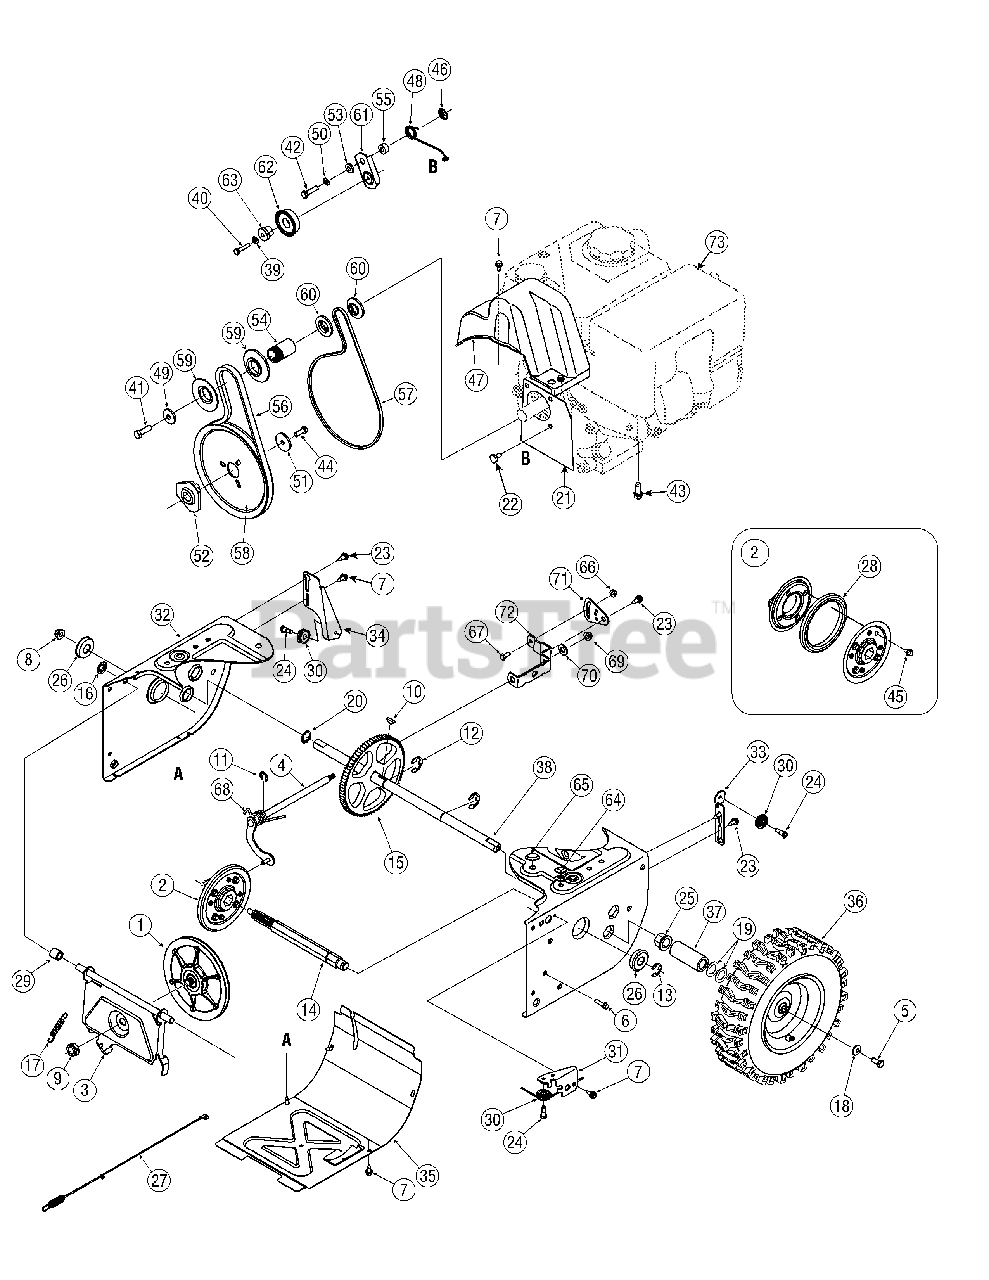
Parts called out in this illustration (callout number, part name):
1	Disc Assembly, Friction Wheel
2	Friction Wheel Assembly, 5.5 OD
3	Support Bracket, Friction Wheel
4	Shift Assembly, Rod
5	Hex Screw, 5/16-24, .750, Gr5
6	Screw, 1/4-20, 1.000
7	Screw, 1/4-20 x .625
8	Nut, Flange Lock, 3/8-16, Nylon
9	Nut, Flange, 5/8-18
10	Key, Hi Pro, 3/16 x 3/4 Dia.
11	E-ring, .500 Dia.
12	E-ring, Retaining, .875 Dia.
13	E-ring, .750 Dia.
14	Hex Shaft, .8125, 7-Tooth
15	Gear, 80-Tooth
16	Speed Nut, .500
17	Extension Spring
18	Washer, Bell, .340 x .872 x .060
19	Washer, Flat, .793 x 1.24 x .060
20	Washer, Flat, .75 x 1.00 x .060
21	Plate, Cover
22	Shoulder Screw
23	Screw, Shoulder, .37 x .105, 1/4-20
24	Screw, 1/4-28, .375
25	Bearing, Hex Flange x .75 ID
26	Bearing, Ball, 17 x 40 x 12
27	Clutch Cable, Wheel, 44.95"
28	Rubber, Friction Wheel, 5.5 OD
29	Spacer, .508 ID x .75 OD x .68
30	Roller, Cable
31	Front Guide Bracket, Auger Cable
32	Frame
33	Guide Bracket, Auger Cable
34	Guide Bracket, Drive Cable
35	Cover, Frame
36	LH Wheel Assembly
36	RH Wheel Assembly
37	Spacer, 1.25 x .75 x 3.0
38	Axle, .75 x 22"
39	Washer, Lock, 1/4
40	Hex Screw, 1/4-20, 1.25, Gr5
41	Hex Screw, 3/8-24, 1.25, Gr8
42	Hex Screw, 5/16-24, 1.25, Gr5
43	Screw, Sems, 3/8-16, 1.00
44	Hex Screw, 5/16-24, .875, Gr8
45	Screw, 1/4-20 x .625
46	Nut, Push-on, .25 Dia.
47	Cover, Belt
48	Spring, Torsion, .850 ID x .354
49	Washer, Flat, .406 x 1.25 x .157
50	Washer, Lock .3125
51	Washer, Flat, .34 x 1.50 x .150
52	Pulley, Adapter, .75 Dia.
53	Spacer, Shoulder, .317 x .50 x .102
54	Spacer, .875 ID x 1.185 OD
55	Spacer, .340 x .750 x .360
56	Belt, Auger Drive
57	Belt, Wheel Drive
58	Pulley, Auger Drive, 8.1 x .5
59	Pulley, Half, V x 2.600 OD
60	Pulley, Half, 3/8-V x 1.7160 OD
61	Idler Bracket, Wheel Drive
62	Idler Pulley Assembly
63	Spacer, Shoulder, .26 x .79 x .538
64	Plug, 3/8 ID
65	Plug, 1/2 ID
66	Nut, Flange Lock, 1/4-20, Nylon
67	Hex Screw, 1/4-20, .620, Gr5
68	Spring, Torsion, .750 ID x .968
69	Nut, Flange Lock, 5/16-18, Nylon
70	Wash., Flat, .469 x .875 x .105
71	Pivot Bracket, Speed Selector
72	Shift Bracket, Speed Selector
73	Replacement Engine
